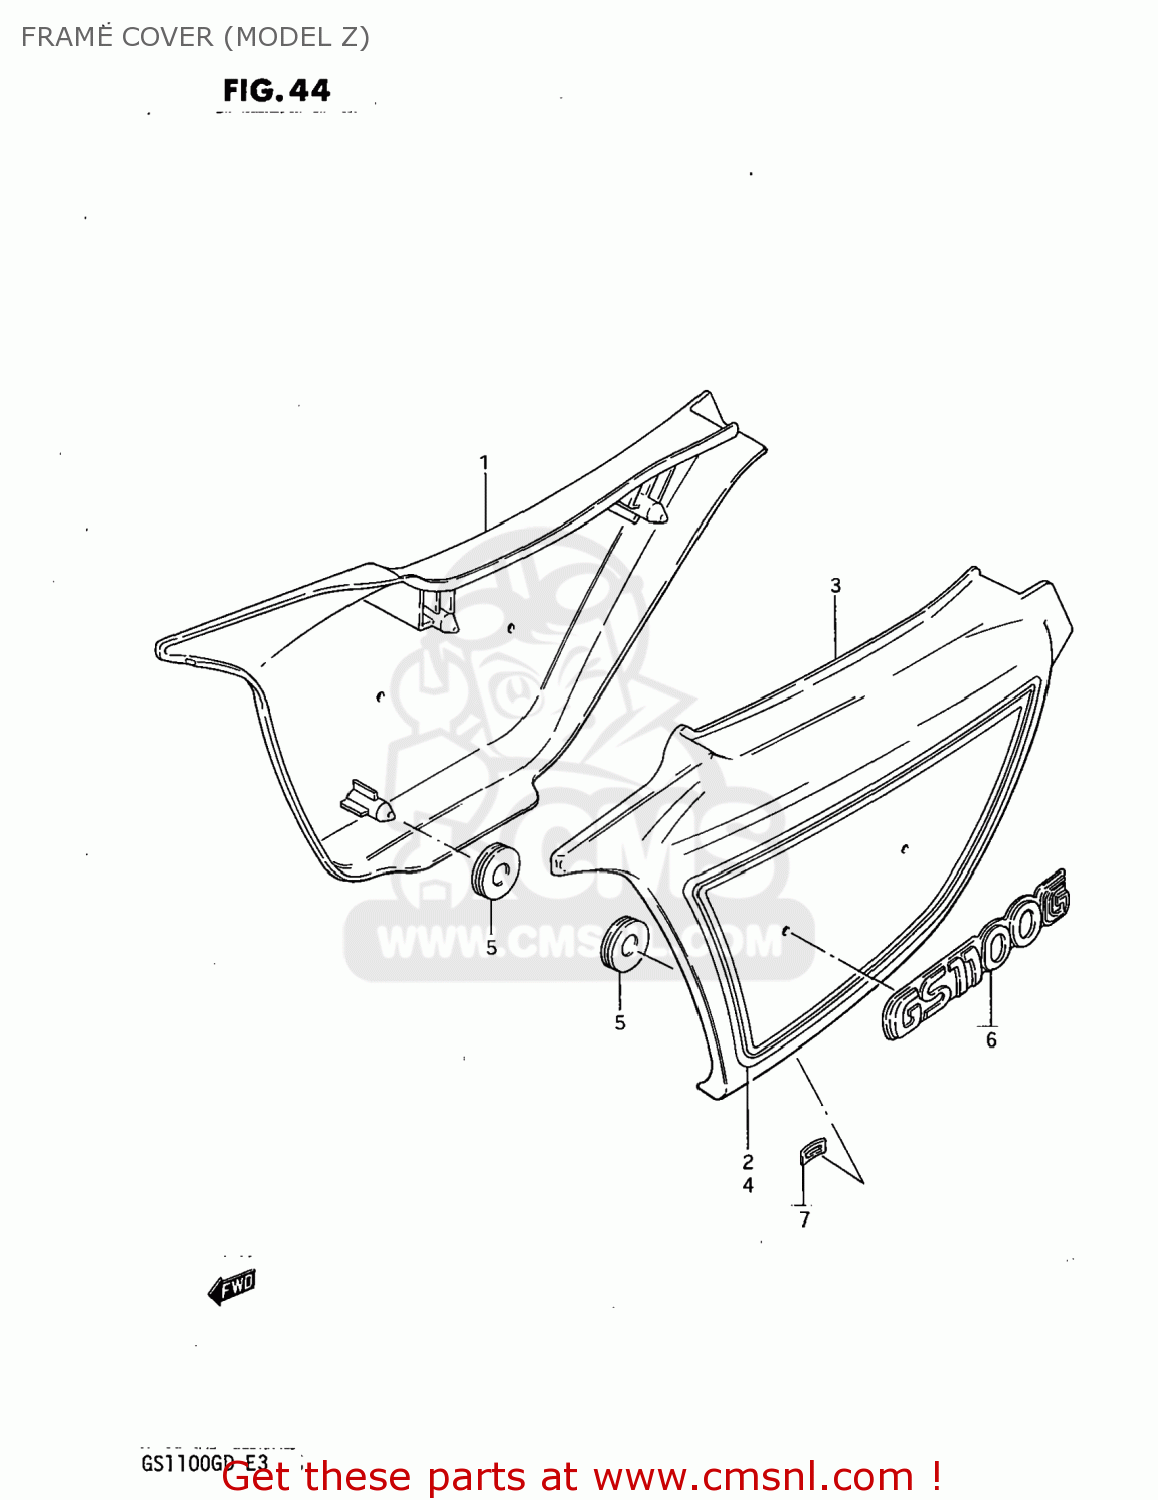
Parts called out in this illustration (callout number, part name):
1	COVER,FRAME,RIGHT
2	TAPE SET,FRAME COVER
3	COVER,FRAME,LEFT
4	TAPE SET,FRAME COVER
5	CUSHION
6	EMBLEM
7	NUT
